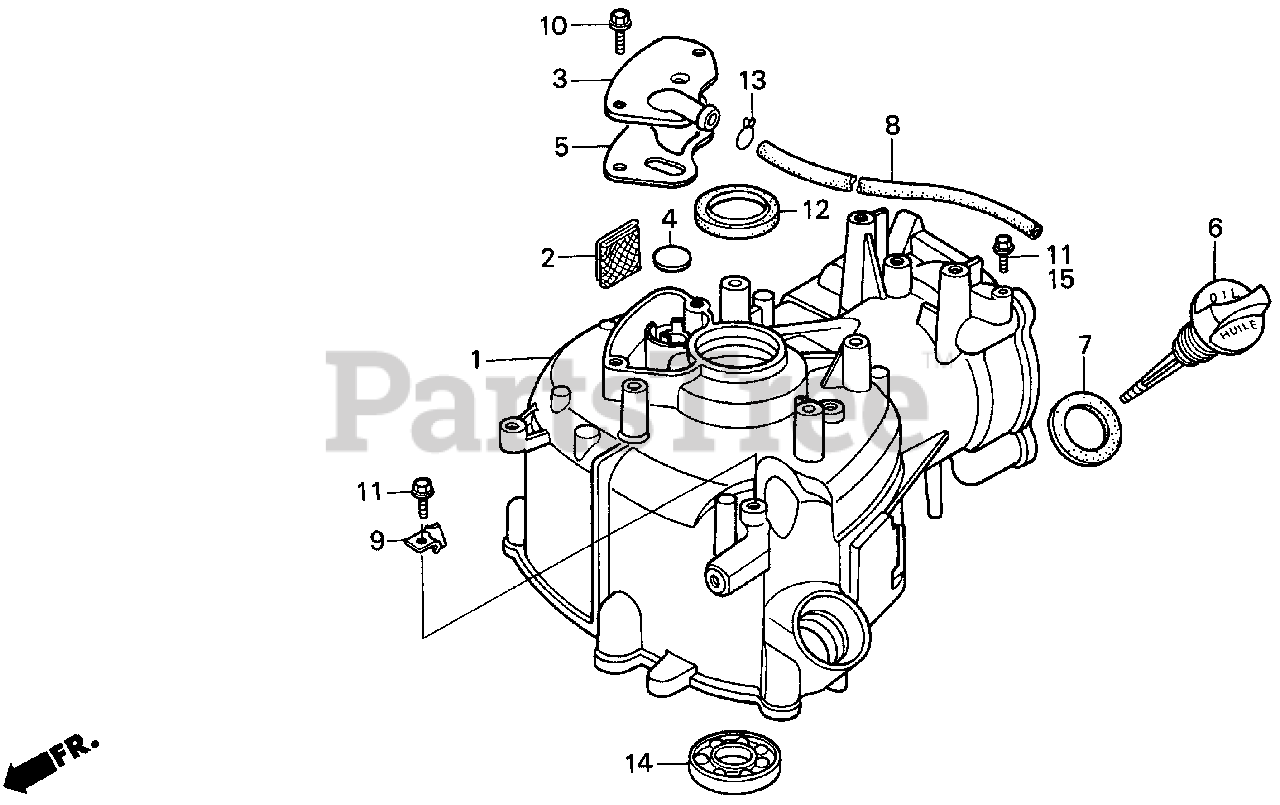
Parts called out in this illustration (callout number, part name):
1	CYLINDER *NH8* (DARK GRAY)
2	FILTER, BREATHER
3	CAP, BREATHER CHAMBER
4	VALVE, BREATHER
5	GASKET, BREATHER CAP
6	CAP, OIL FILLER
7	GASKET, OIL FILLER CAP
8	TUBE, BREATHER
9	CLAMP, BREATHER TUBE
10	BOLT, FLANGE (6X12)
11	BOLT, FLANGE (5X10)
12	OIL SEAL (25X38X7)
12	OIL SEAL (25X38X7) (ARAI)
13	CLIP, TUBE (B12)
14	BEARING, RADIAL BALL (6205)
